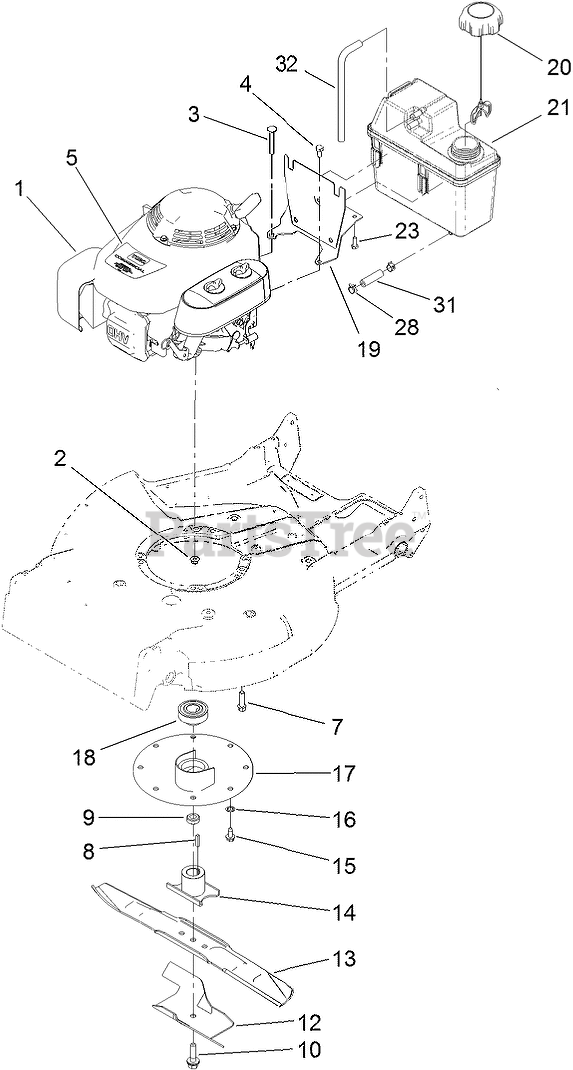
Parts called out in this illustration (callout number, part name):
2	NUT-HF
3	Screw-CARR
4	SCREW-HH
5	DECAL-ENGINE, HONDA
7	SCREW-SHOULDER
8	KEY-SQUARE
9	Spacer-Retainer, Blade
10	BOLT-BLADE
12	STIFFENER-BLADE
13	BLADE-21 INCH
14	RETAINER-BLADE
15	SCREW-HWHTF
16	WASHER-LOCK, INTERNAL
17	PROTECTOR-CRANKSHAFT
18	PULLEY-DRIVER
19	MOUNT-TANK
20	CAP-RATCHET, TETHERED
21	TANK-FUEL
23	SCREW-HWH
28	CLAMP-HOSE
31	HOSE-FUEL
32	HOSE-VENT, CANISTER
